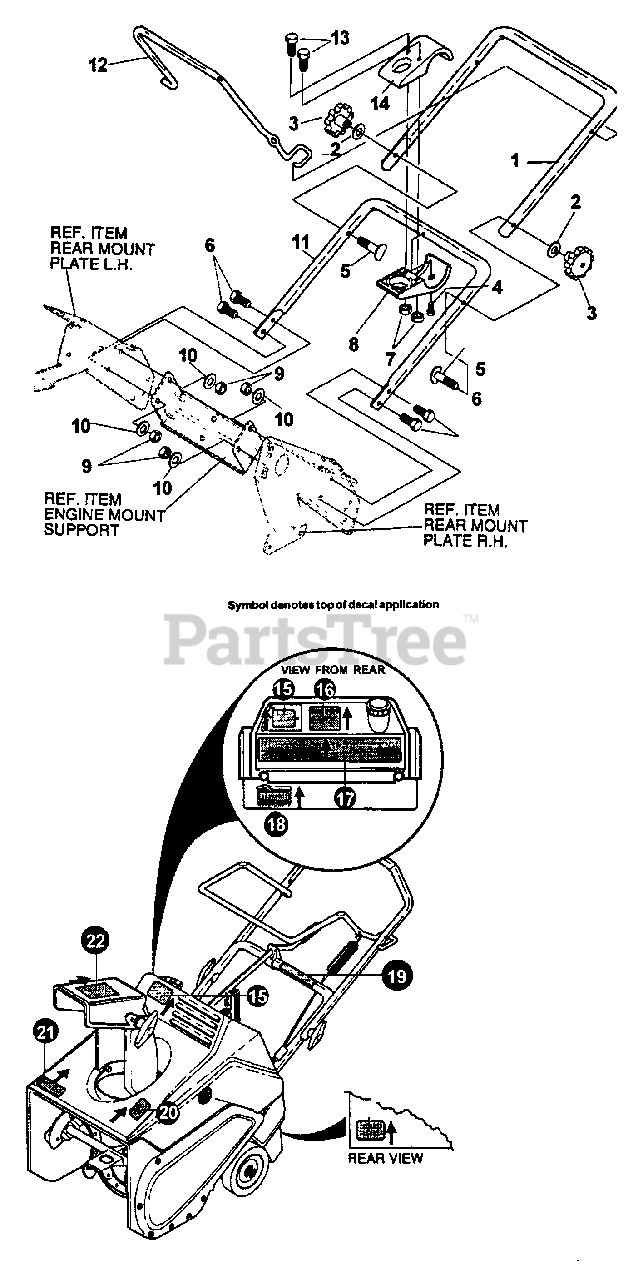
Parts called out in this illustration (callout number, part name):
1	HANDLE, UPPER
2	WASHER
4	SCREW 1/4"-20×0.63
5	BOLT, 5/16-18×2.00
6	SCREW 5/16"-18×0.75
7	NUT, 10-24
8	BRKT HALF, CHUTE CRANK
9	NUT, 5/16"-18
10	WASHER
11	HANDLE, LOWER
12	BAR, DRIVE CONTROL LOOP
13	SCREW #10-24×1.00
14	BRKT HALF, CHUTE CRANK
15	LABEL - ECHO -- ST-5000E
16	LABEL - STARTING
17	LABEL - CONTROL PANEL
18	LABEL - CHOKE
19	LABEL - AUGER CONTROL BAR
20	LABEL - DANGER
21	LABEL - ECHO
22	LABEL - DANGER
